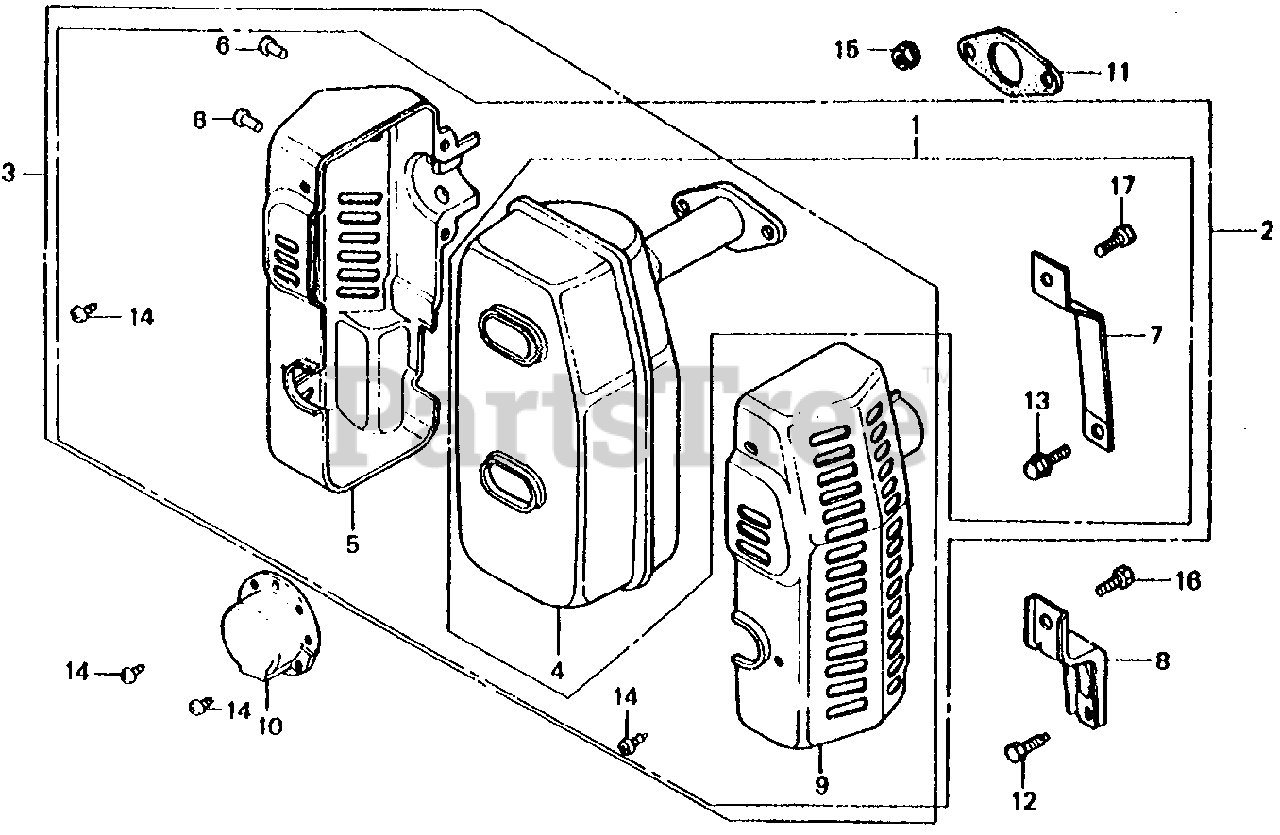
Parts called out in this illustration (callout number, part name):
1	MUFFLER KIT
2	MUFFLER KIT (NOT AVAILABLE)
3	MUFFLER ASSY.
4	MUFFLER
5	PROTECTOR, L. MUFFLER
6	RIVET (4X5)
7	STAY, MUFFLER
8	STAY, MUFFLER
9	PROTECTOR, R. MUFFLER
10	CAP, MUFFLER
11	GASKET, MUFFLER
12	BOLT, FLANGE (6X12) (CT200)
13	BOLT, FLANGE (8X18) (NOT AVAILABLE)
14	SCREW, TAPPING (4X8)
15	NUT, FLANGE (8MM)
16	BOLT, FLANGE (6X10)
17	BOLT, FLANGE (6X12)
